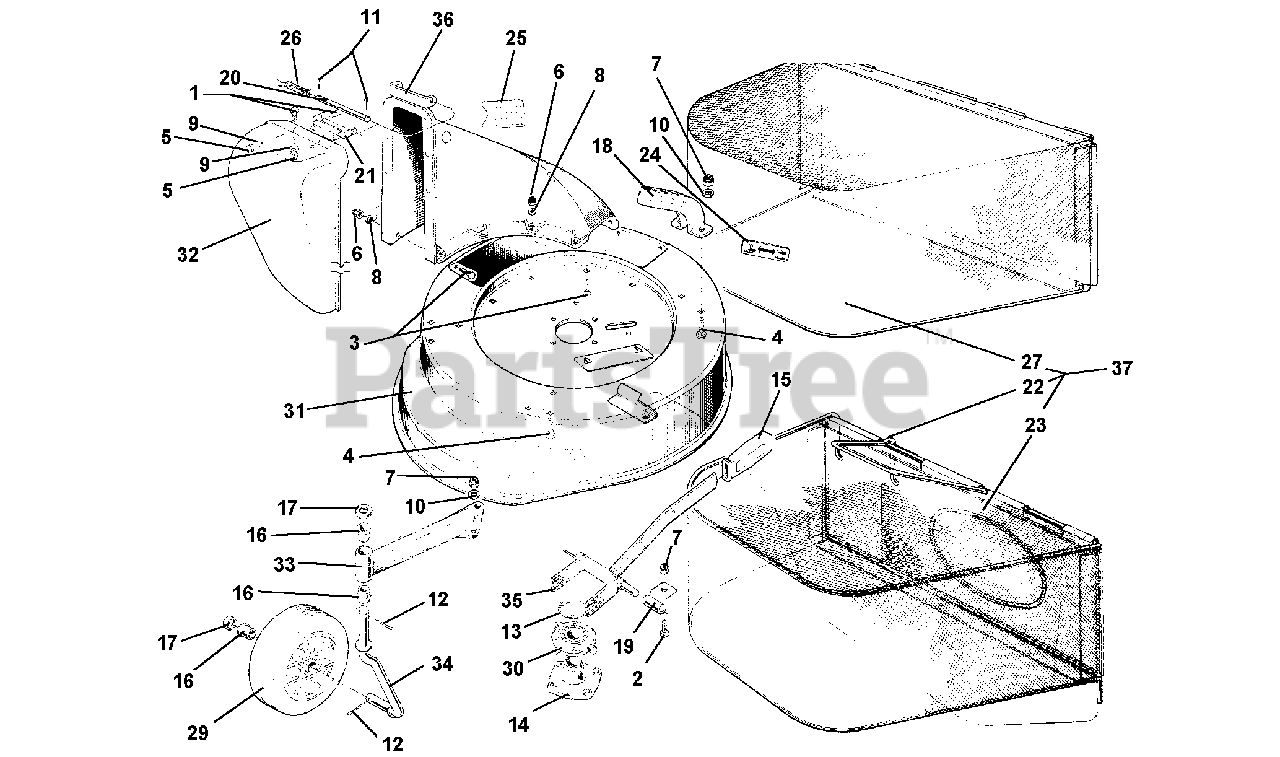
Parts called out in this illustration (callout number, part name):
1	SCREW M5 X 10
2	SCREW M8 X 16
3	SCREW M6 X 20
4	SCREW TTQ M8 X 20 UNI 5731
6	NUT, SELF LOCKING M6
7	NUT, SELF LOCKING M8
8	WASHER, FLAT 6.4
9	SUPER WASHER
10	WASHER, LOCK 8.4
12	PIN, COTTER 4 X 25
13	EXT. CIRCLIP D 35
14	BLADE HOLDER HUB
18	CUTTING HEIGHT SELECTOR
24	TRANSFER FOR LAWN MOWER
26	DEFLECTOR SPRING
29	SMALL WHEEL
31	LAWN MOWER CRANKCASE
33	WHEEL SUPPORT
35	ADJUSTING LEVER
37	CATCHER COMPLETE
